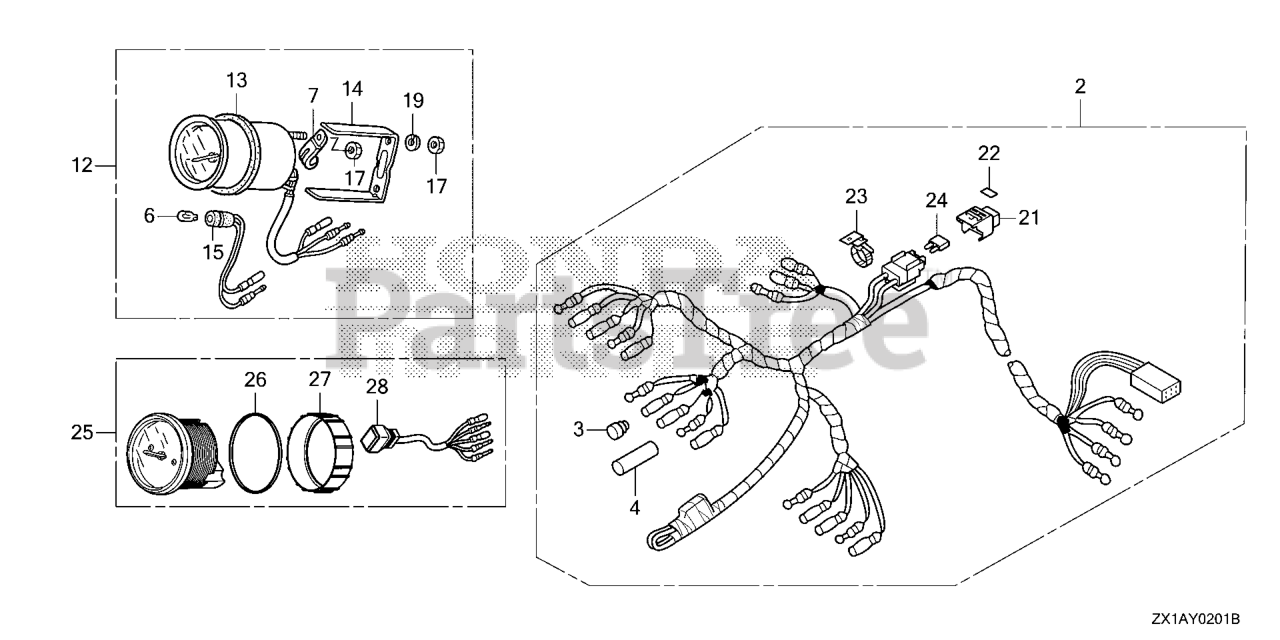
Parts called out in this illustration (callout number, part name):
1	BAND B1, CABLE Use up to Frame SN 1001879.
2	HARNESS ASSY., METER (A)
3	PLUG, CONNECTOR (INNER) (TROLLING CONTROL)
4	PLUG, CONNECTOR (OUTER) (ENGINE NO.)
5	BULB, WEDGE BASE (T10) (12V 1.7W) (STANLEY)
6	BULB, WEDGE BASE (12V1.7W) (TOSHIBA)
7	CLAMP
8	TACHOMETER ASSY.
9	GASKET
10	BRACKET (TO 1015209) (FROM 1015210)
11	SOCKET (TO 1015209) (FROM 1015210)
12	METER ASSY., TRIM
13	GASKET (TO 1015209) (FROM 1015210)
14	BRACKET (TO 1015209) (FROM 1015210)
15	SOCKET (TO 1015209) (FROM 1015210)
16	NUT, HEX. (5MM)
17	NUT, HEX. (4MM)
18	WASHER, SPRING (5MM)
19	WASHER, SPRING (4MM)
20	FUSE A (10A)
21	COVER ASSY., FUSE
22	LABEL, FUSE (10A)
23	HOLDER, CONNECTOR (128.6MM) (NATURAL)
24	FUSE, MINI (10A)
25	TACHO METER KIT
26	CUSHION RUBBER
27	RING
28	WIRE ASSY.
